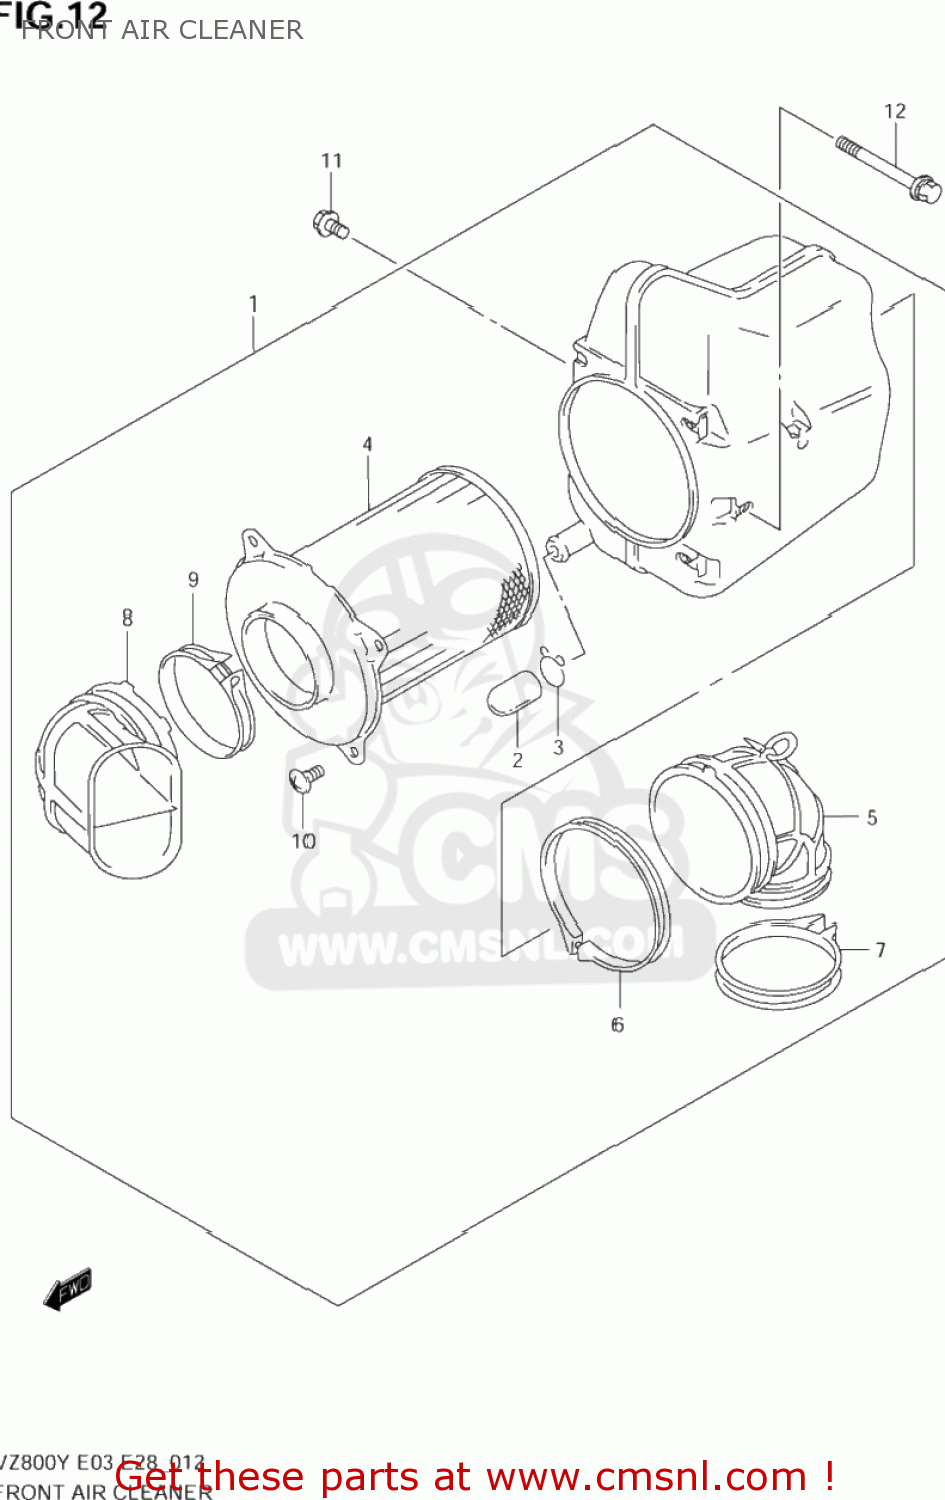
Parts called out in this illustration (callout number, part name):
1	CLEANER ASSY,AIR FR
2	PLUG
3	CLIP
4	FILTER ASSY
5	TUBE,AIR CLEANER OUTLET
6	CLAMP
7	CLAMP
8	TUBE,INLET
9	CLAMP
10	SCREW
11	BOLT
12	BOLT
